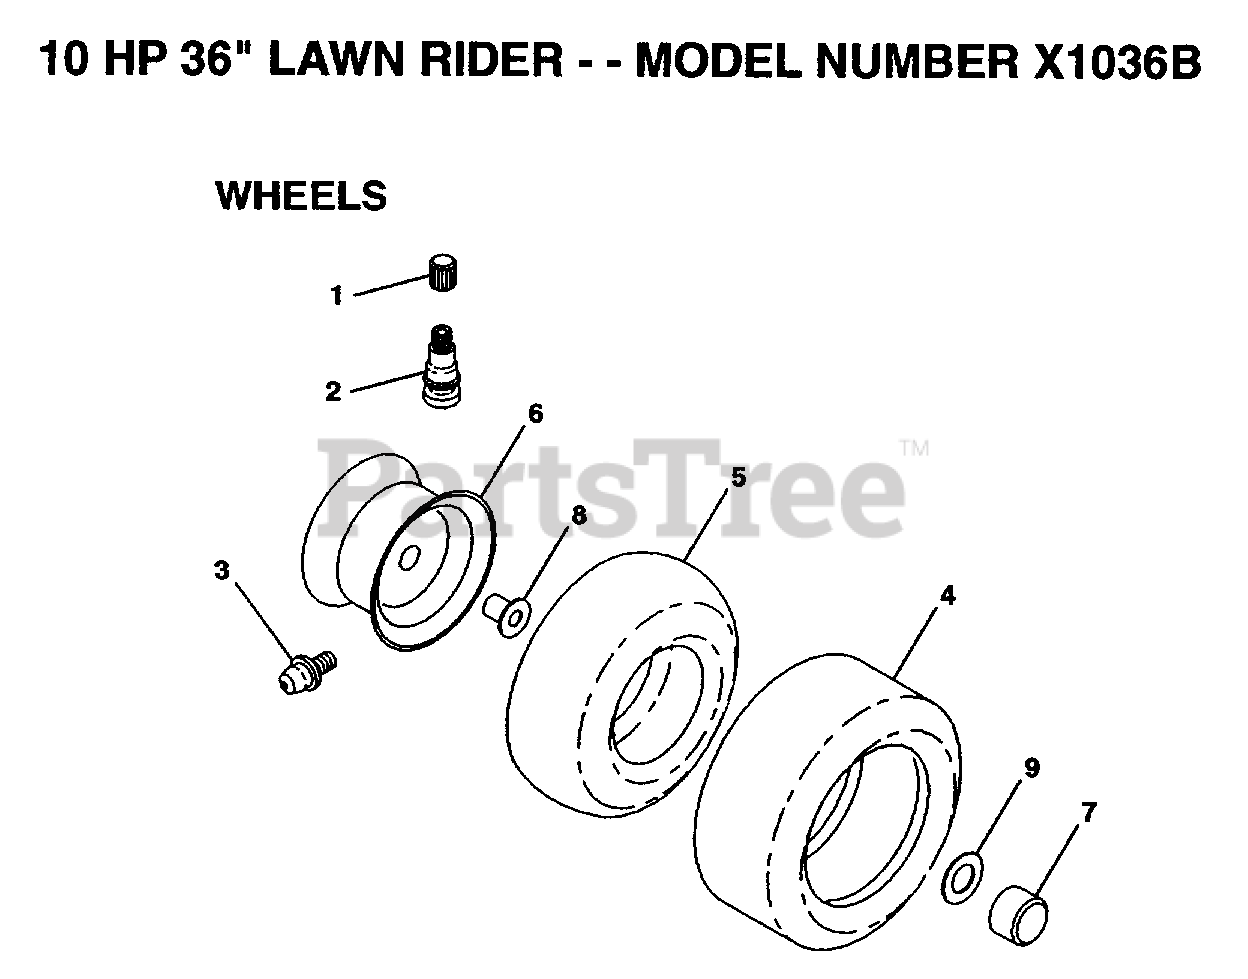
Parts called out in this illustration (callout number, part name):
1	VALVE CAP
2	VALVE STEM LT
3	FITTING LT
5	TUBE.5.3/4.5/6
5A	TUBE.16X6.5/7.5-8
7	HUB CAP
8	"FLANGE, BEARING"
9	WASHER
